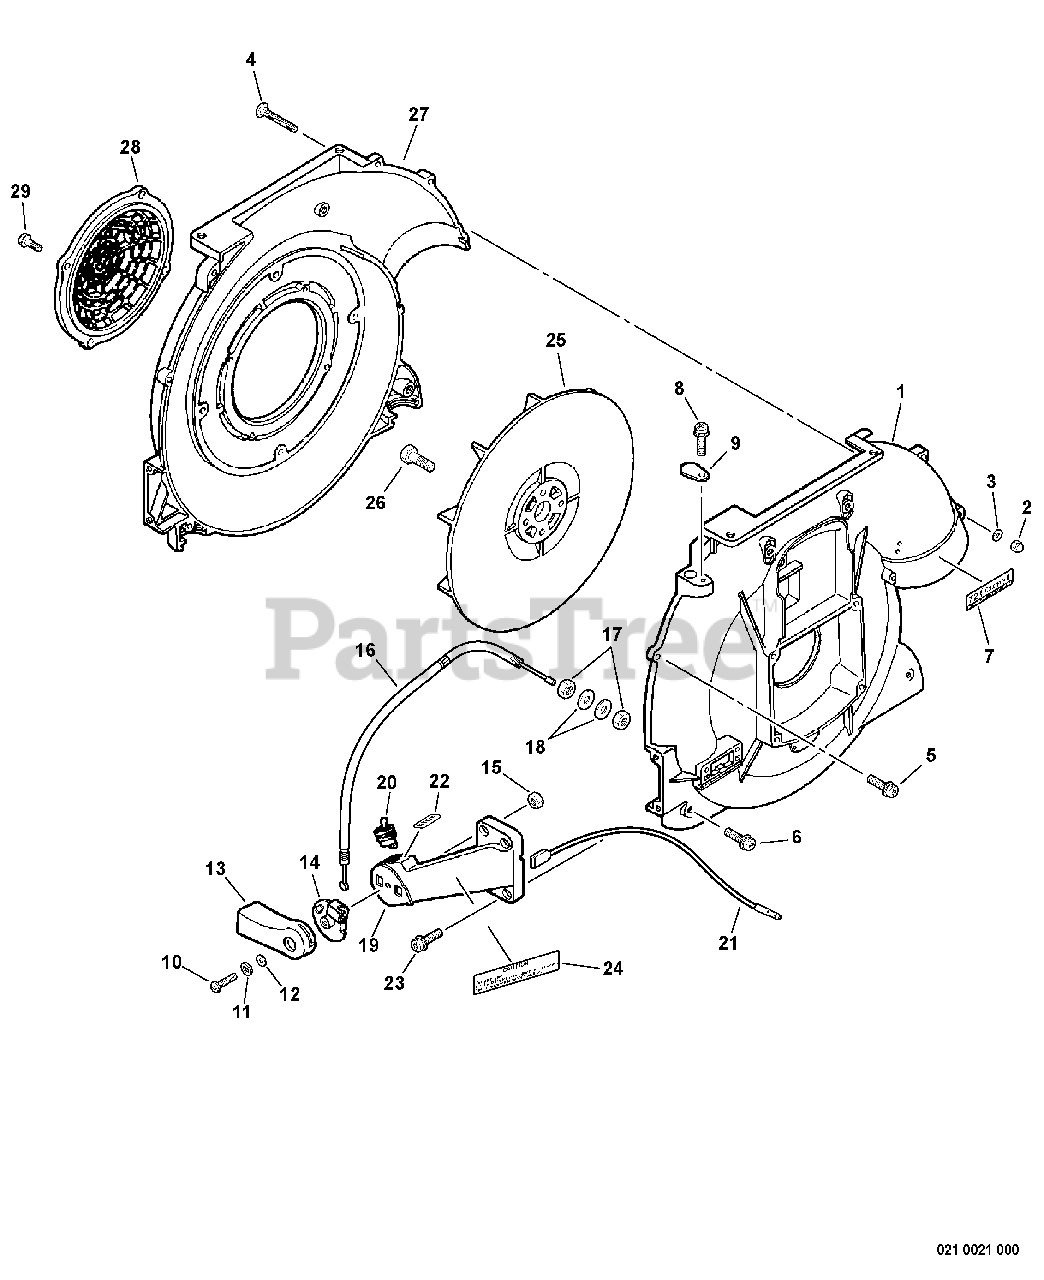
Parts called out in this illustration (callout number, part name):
1	COVER, FAN - OUTER
2	NUT - 5 -- CAP
3	WASHER, FLAT 5.5×10×0.8
5	SCREW 5×20
6	SCREW 5×25
7	LABEL - NOISE
8	SCREW 5×10
10	SCREW 6×25
11	WASHER, SPRING 6
13	CONTROL, THROTTLE
15	NUT, HEX M6
16	CABLE, THROTTLE
18	WASHER 6.5×13×1
19	MOUNT, THROTTLE LEVER
20	IGNITION SWITCH ASSY
22	LABEL, ON-OFF
23	SCREW 5×20
24	LABEL - CAUTION
27	COVER, FAN - INNER -- ORANGE
28	SHIELD, DEBRIS
